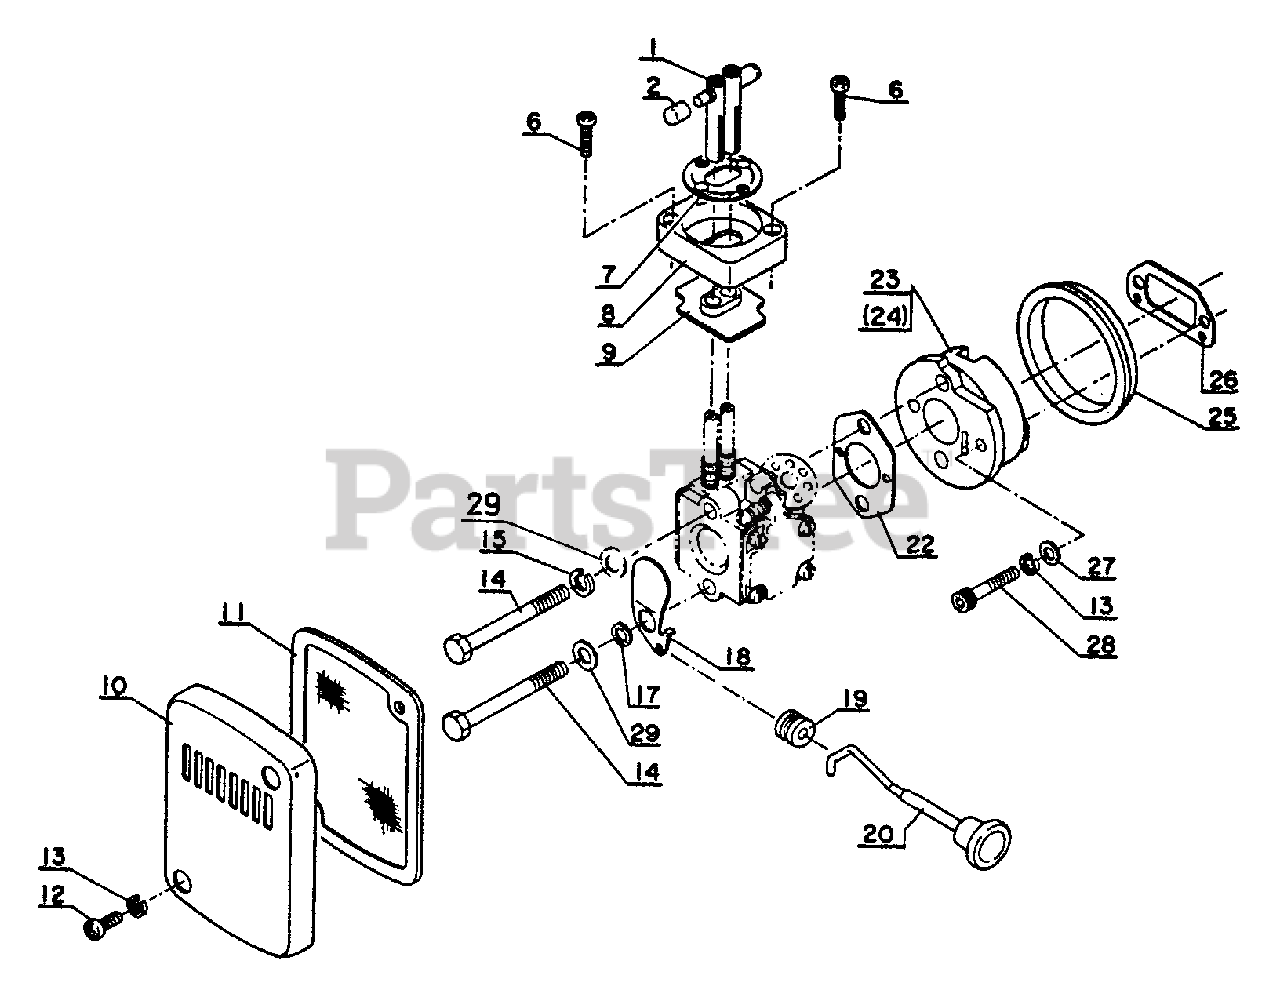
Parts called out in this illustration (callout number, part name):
1	ADJUSTING ARM
2	ADJUSTING KNOB
6	SCREW 3×10
7	LABEL - DECOMPRESSION
8	FRAME
9	GROMMET
10	COVER, AIR FILTER
11	FILTER, AIR
12	SCREW 4×12
13	WASHER, SPRING 4 MM
14	BOLT 5×40
15	WASHER, SPRING 5
17	WASHER 5.2×8×0.8T
18	SHUTTER, CHOKE
19	GROMMET, CHOKE
20	ROD, CHOKE
22	GASKET, INTAKE
23	INSULATOR
25	CARBURETOR RUBBER GROMMET
26	GASKET, INTAKE
27	WASHER 4 MM
28	BOLT, HEX 4×20
29	WASHER, FLAT 5.5×10×0.8
